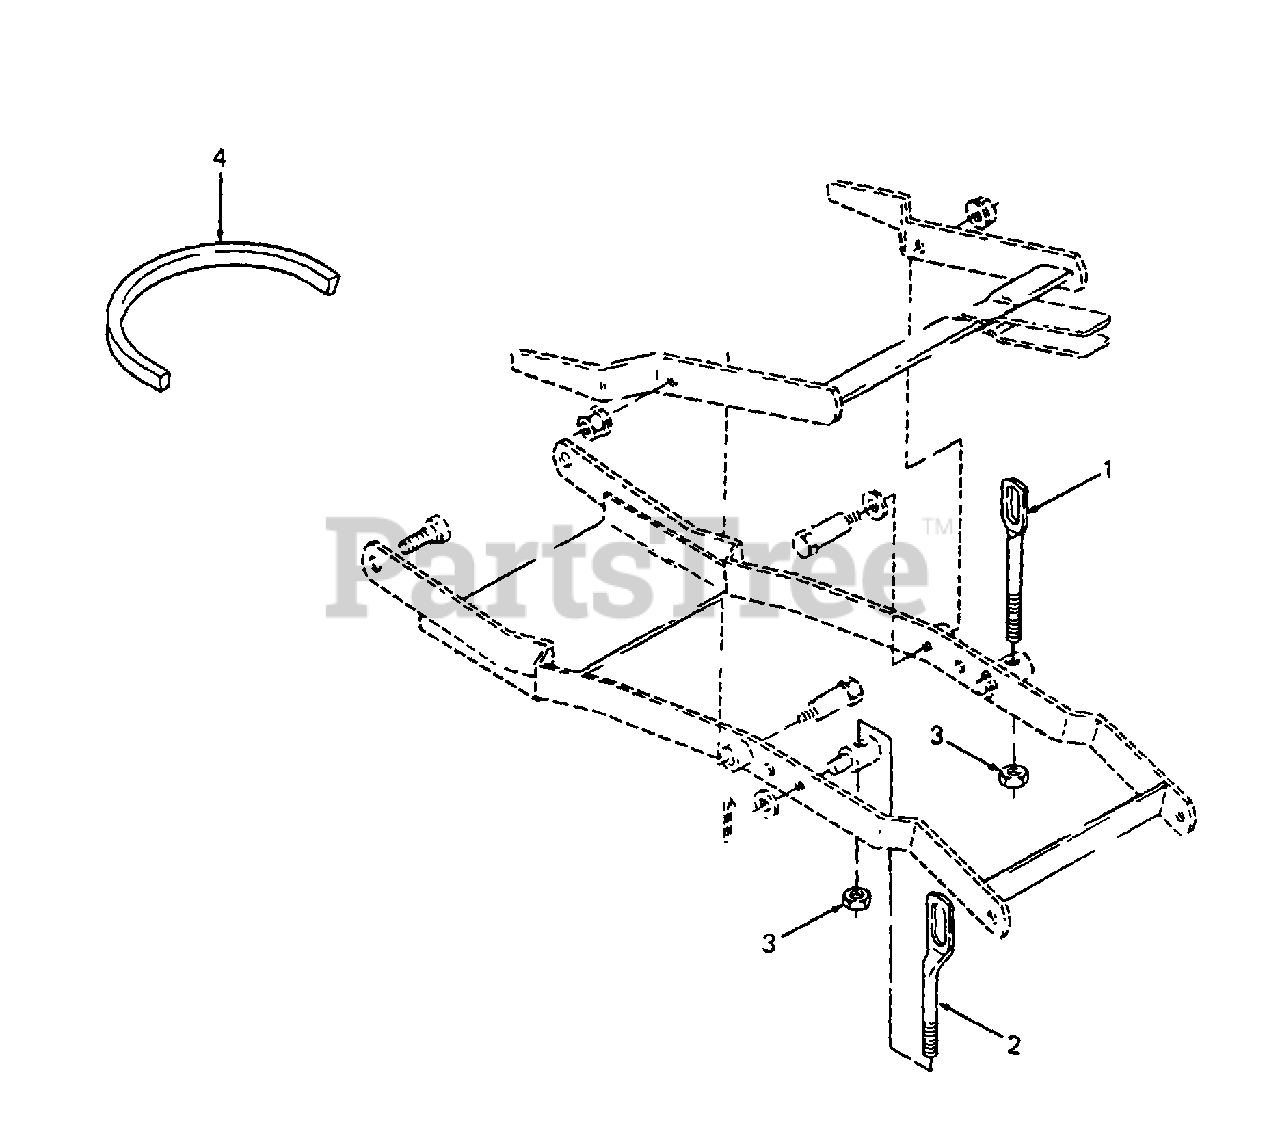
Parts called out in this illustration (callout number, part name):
1	Link. Adjustable, 6.25 Lg
2	Link, Offset Adjustable, 6.35 Lg
3	Nut, Hex Center Lock, 1/2-20
4	Belt, PTO, B Section X 91.68 Lg
